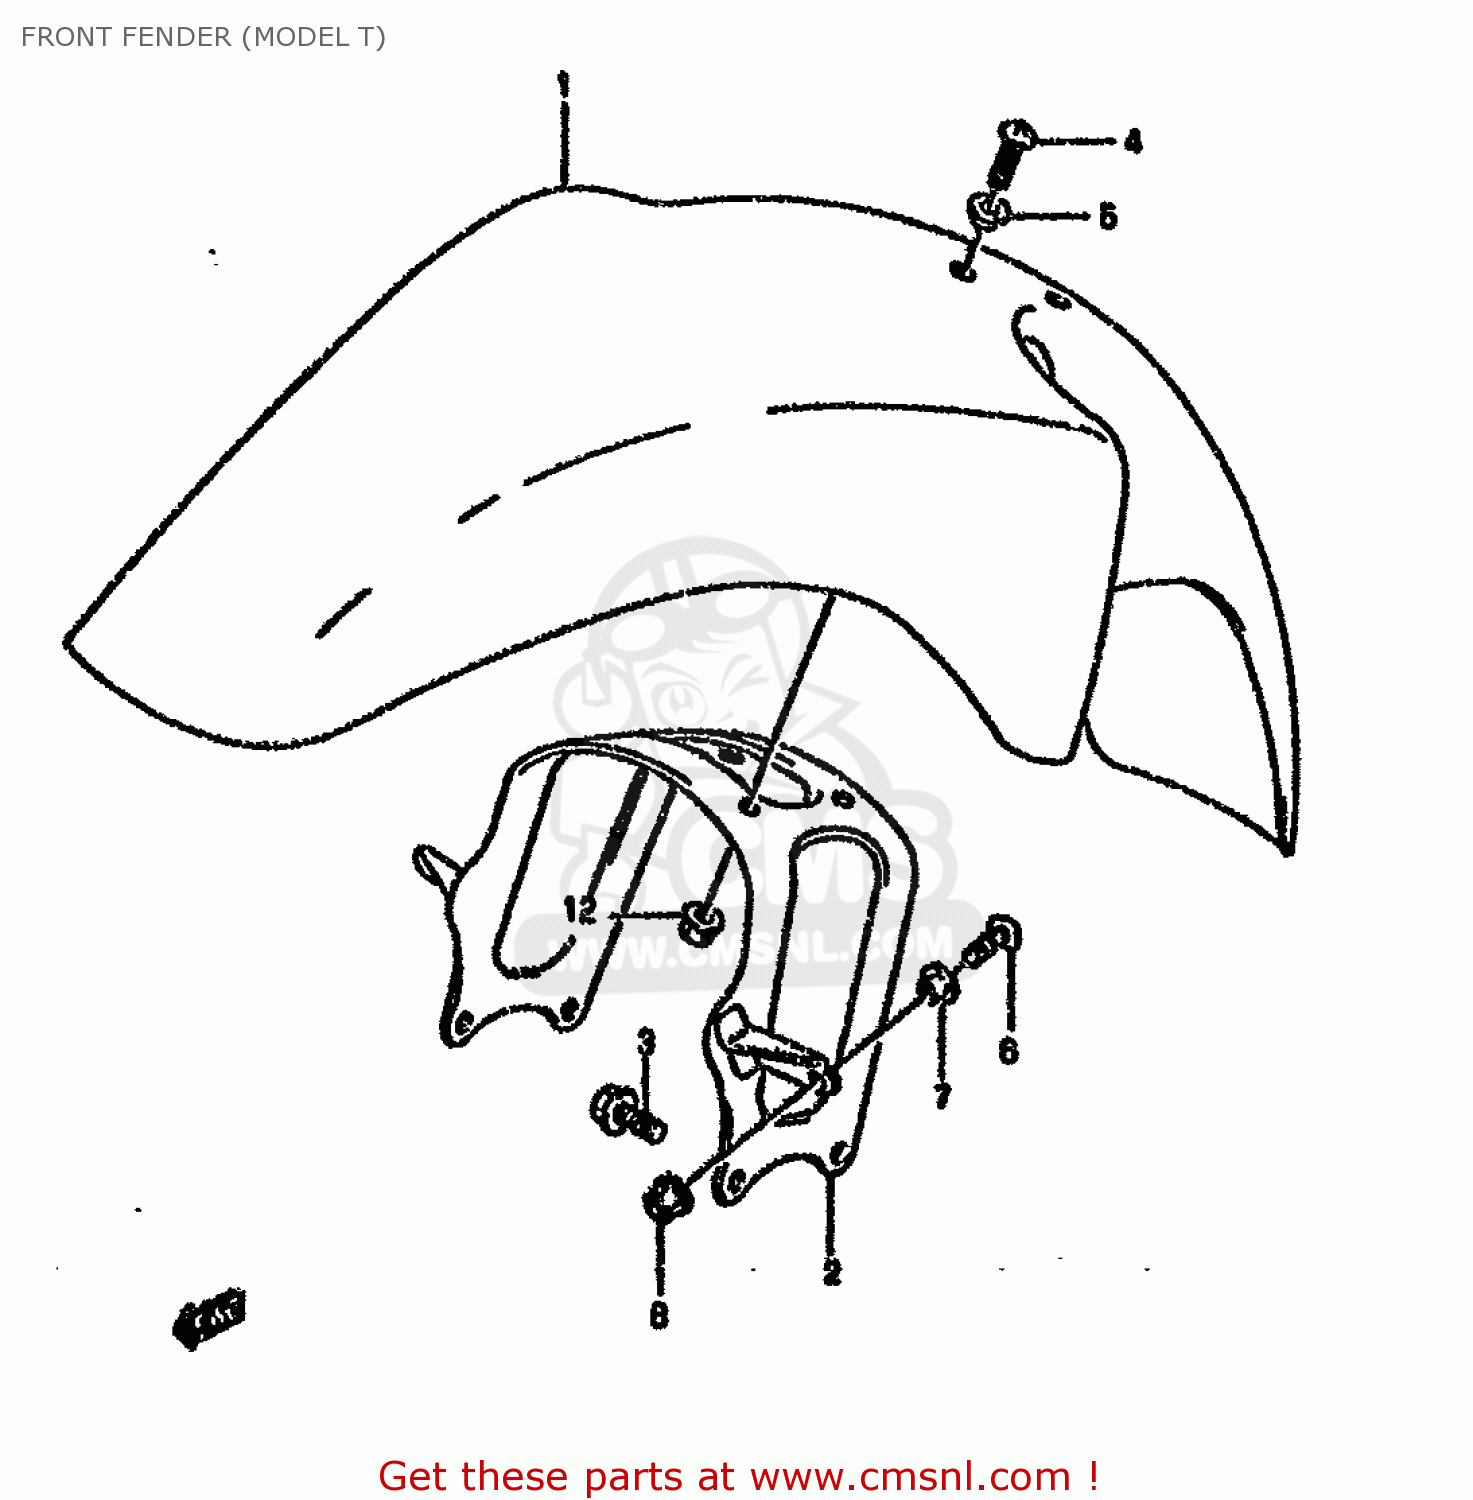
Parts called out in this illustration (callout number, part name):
1	FENDER,FRONT
2	BRACE,FR FENDER
3	BOLT 6X16
4	TAPE,FENDER
5	FENDER,FRONT (BLUE)
6	SCREW
7	WASHER
8	SCREW
9	WASHER
10	SCREW
11	WASHER
12	NUT
